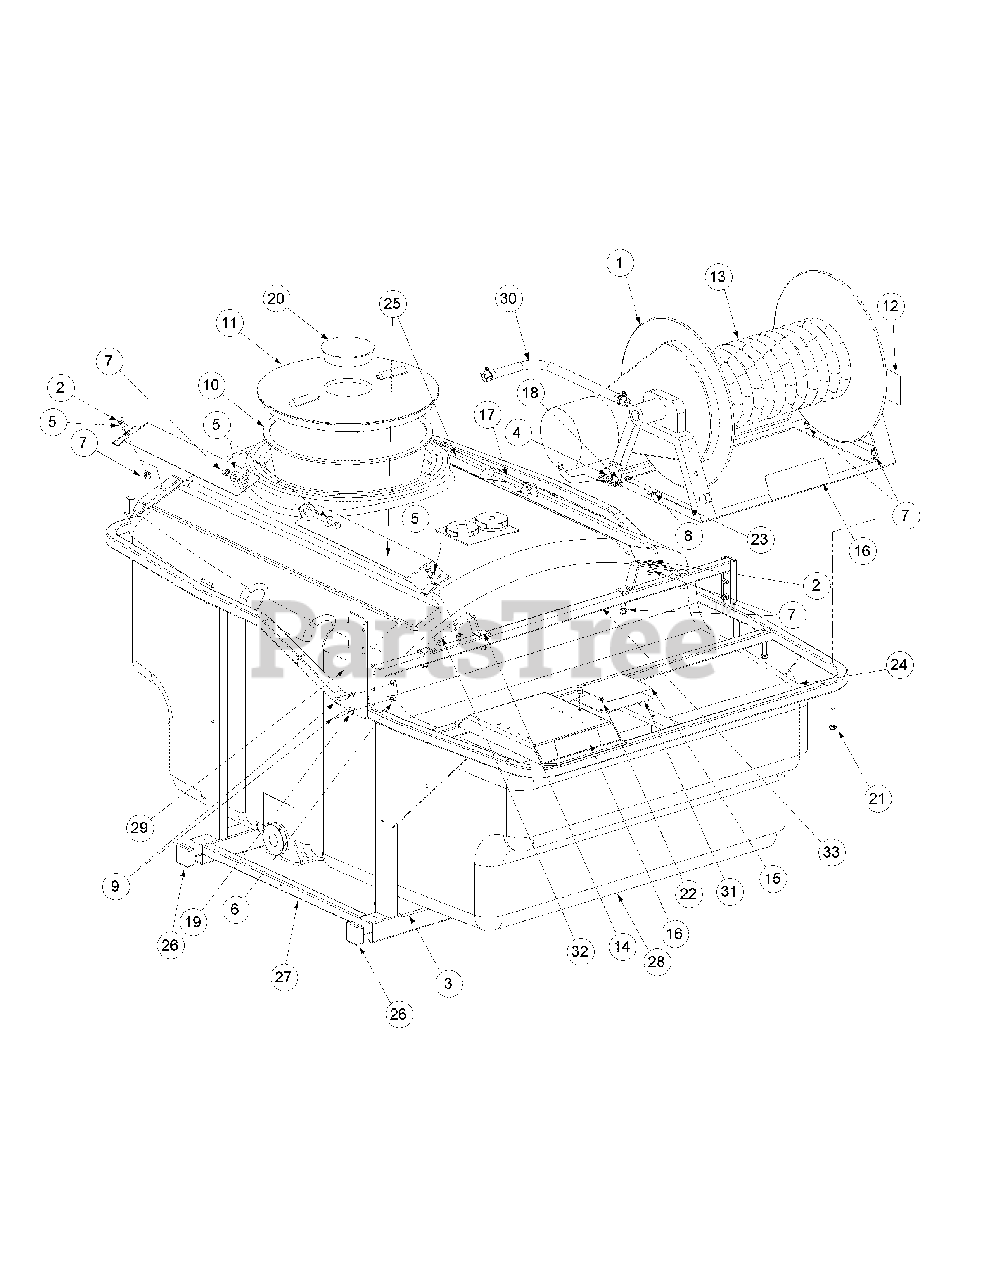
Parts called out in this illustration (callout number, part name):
1	Electric Hose Reel
2	Capscrew, 3/8-16 x 1
3	Adhesive Foam, 4" (sold by the foot)
4	Terminal Ring, 3/8
5	Flat Washer, 3/8
6	Nylock Nut, 5/16-18
7	Nylock Nut, 3/8-16
8	Cable Tie, 3/16 x 7
9	Hex Cap Screw, 5/16-18, 1-1/2
10	Basket Strainer, 16"
11	Threaded Tank Lid, 16" w/ref. #20
12	Decal, Maximum Hose Length
13	Hose Assembly, 800 PSI, 1/2" x 300'
13	Hose Assembly, 600 PSI, 3/8" x 300’
14	Carriage Bolt, 3/8-16, 2
15	Decal, Safety Procedures
16	Decal, 2-3/8 x 7-1/8
17	Capscrew, 3/8-16 x 5
18	Flat Washer, 1/4
19	Flat Washer, 5/16"
20	Vent Check Ball
21	Capscrew, 3/8-16 x 1.75
22	Hex Index Washer Screw, 1/4-20, 1/2 Long
23	Wiring Harness
24	Label, Clear Overlayment
25	200 Gallon Poly Tank Strap
26	Square Tube Plug
27	Main Frame Assembly
28	200 Gallon Poly Pick-up Tank
29	Strainer Manifold Mount Bracket
30	Pump To Reel Hose Assembly
31	Safety Procedure Decal Plate
32	Tank Frame Mount Strap
33	200 Gallon Pickup Mounting Strap
